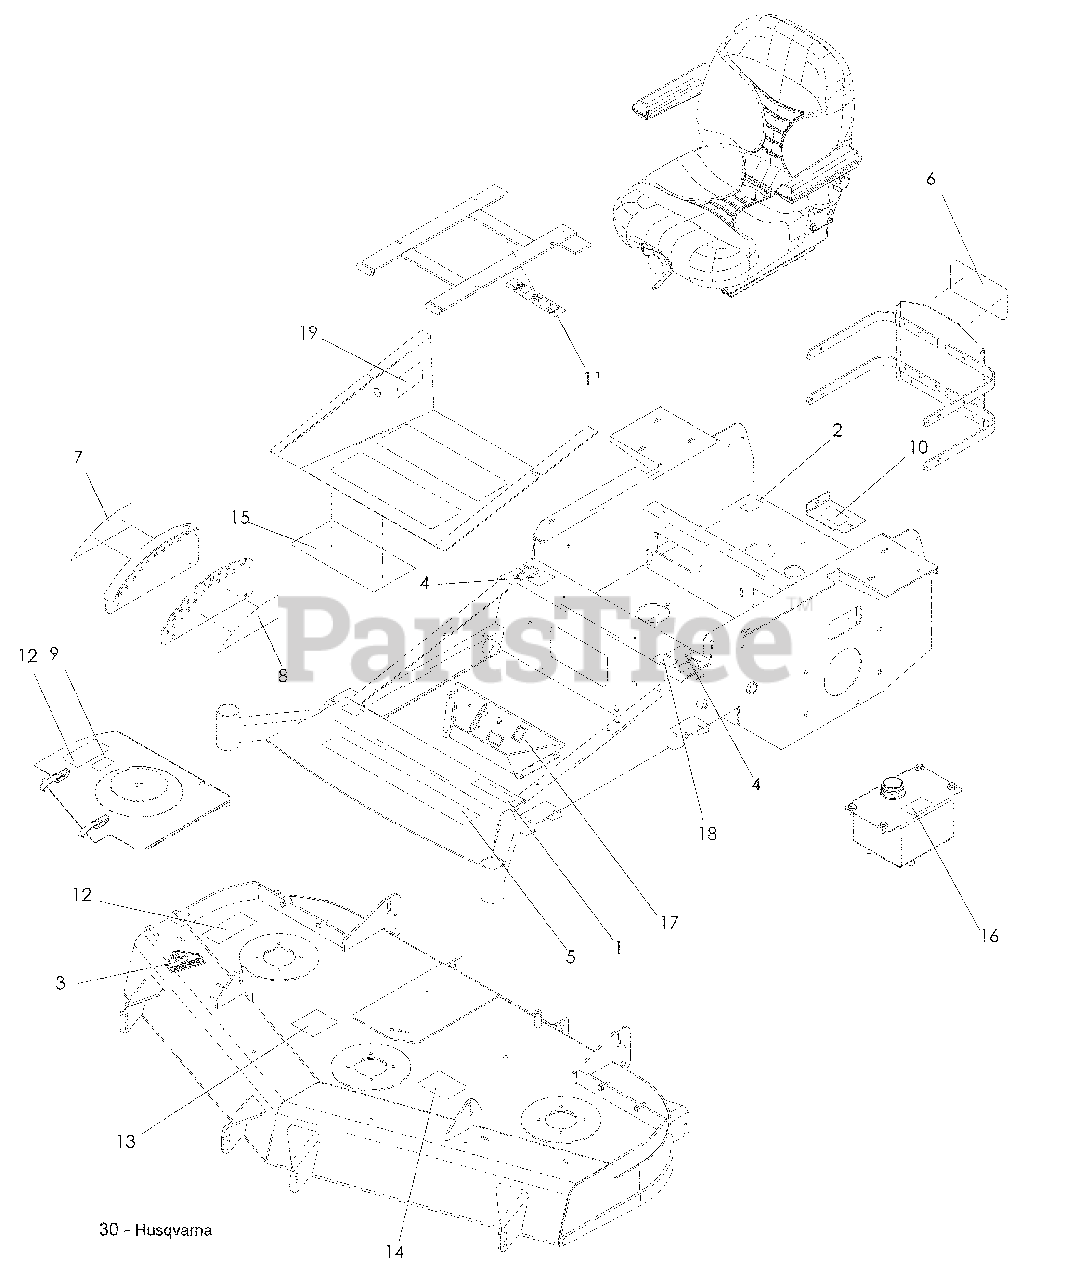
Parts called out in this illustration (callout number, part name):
1	DECAL, LZ5227
2	DECAL, PROP 65
3	DECAL, WARNING
4	DECAL, MOTION CONTROL
5	DECAL, HUSQVARNA
6	DECAL, HUSQVARNA CRWN
7	DECAL, HEIGHT INDICATOR
8	DECAL, HEIGHT INDICATOR
9	DECAL, NO STEP
10	DECAL, DANGER BELT DR
11	DECAL, BATTERY WARNING
12	DECAL, SEVERING
13	DECAL, ANTI-SCALP
14	DECAL, BELT ROUTING
15	DECAL, SERVICE
16	DECAL, OIL TANK
17	DECAL, CONSOLE
18	DECAL, TRACKING
19	DECAL, WARNING
